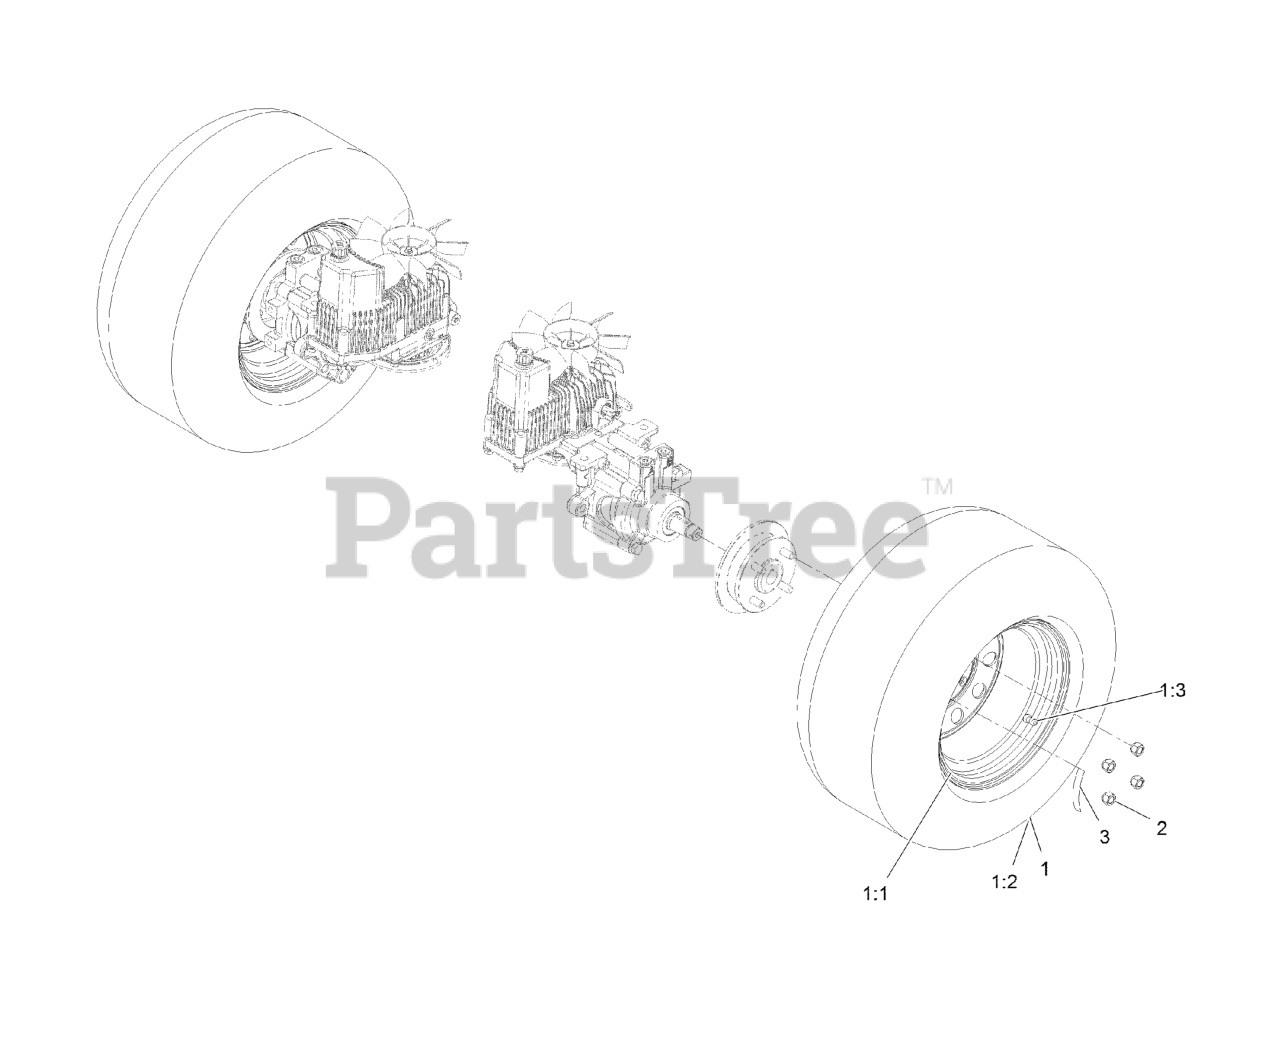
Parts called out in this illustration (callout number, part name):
1	WHEEL AND TIRE ASM
1:3	Stem-Valve
2	NUT-LUG
3	DECAL-TORQUE, WHEEL HUB LUG
